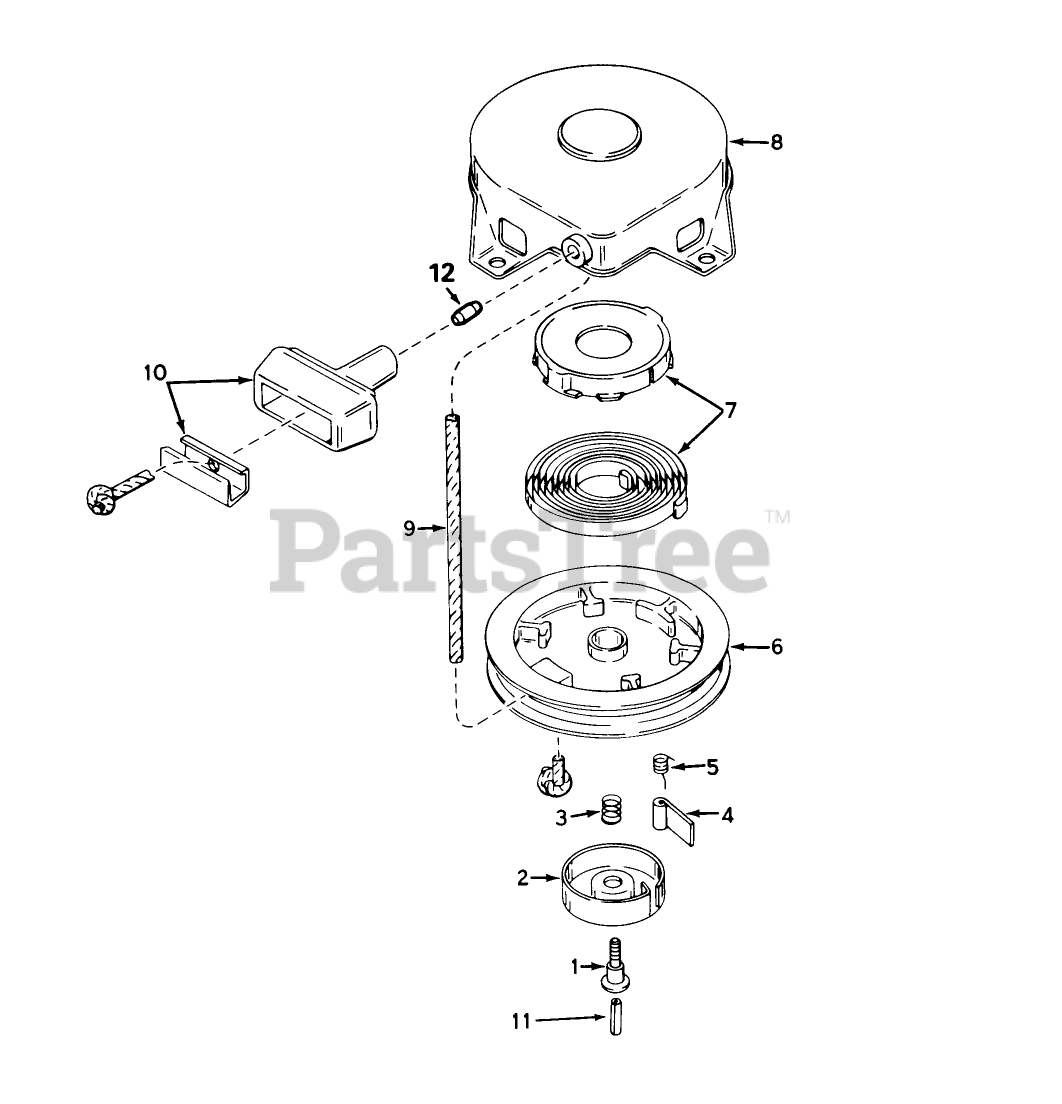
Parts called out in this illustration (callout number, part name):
1	Screw
2	Retainer
3	Spring-Brake
4	Dog-Starter
5	Spring-Dog
6	Pulley
7	Spring Keeper Assy
8	Housing Assy., Starter (Incl. Ref. #1)
9	Rope-Starter (98 cut to length)
10	Assy., Starter
11	Centering
12	Retainer-Starter Rope
